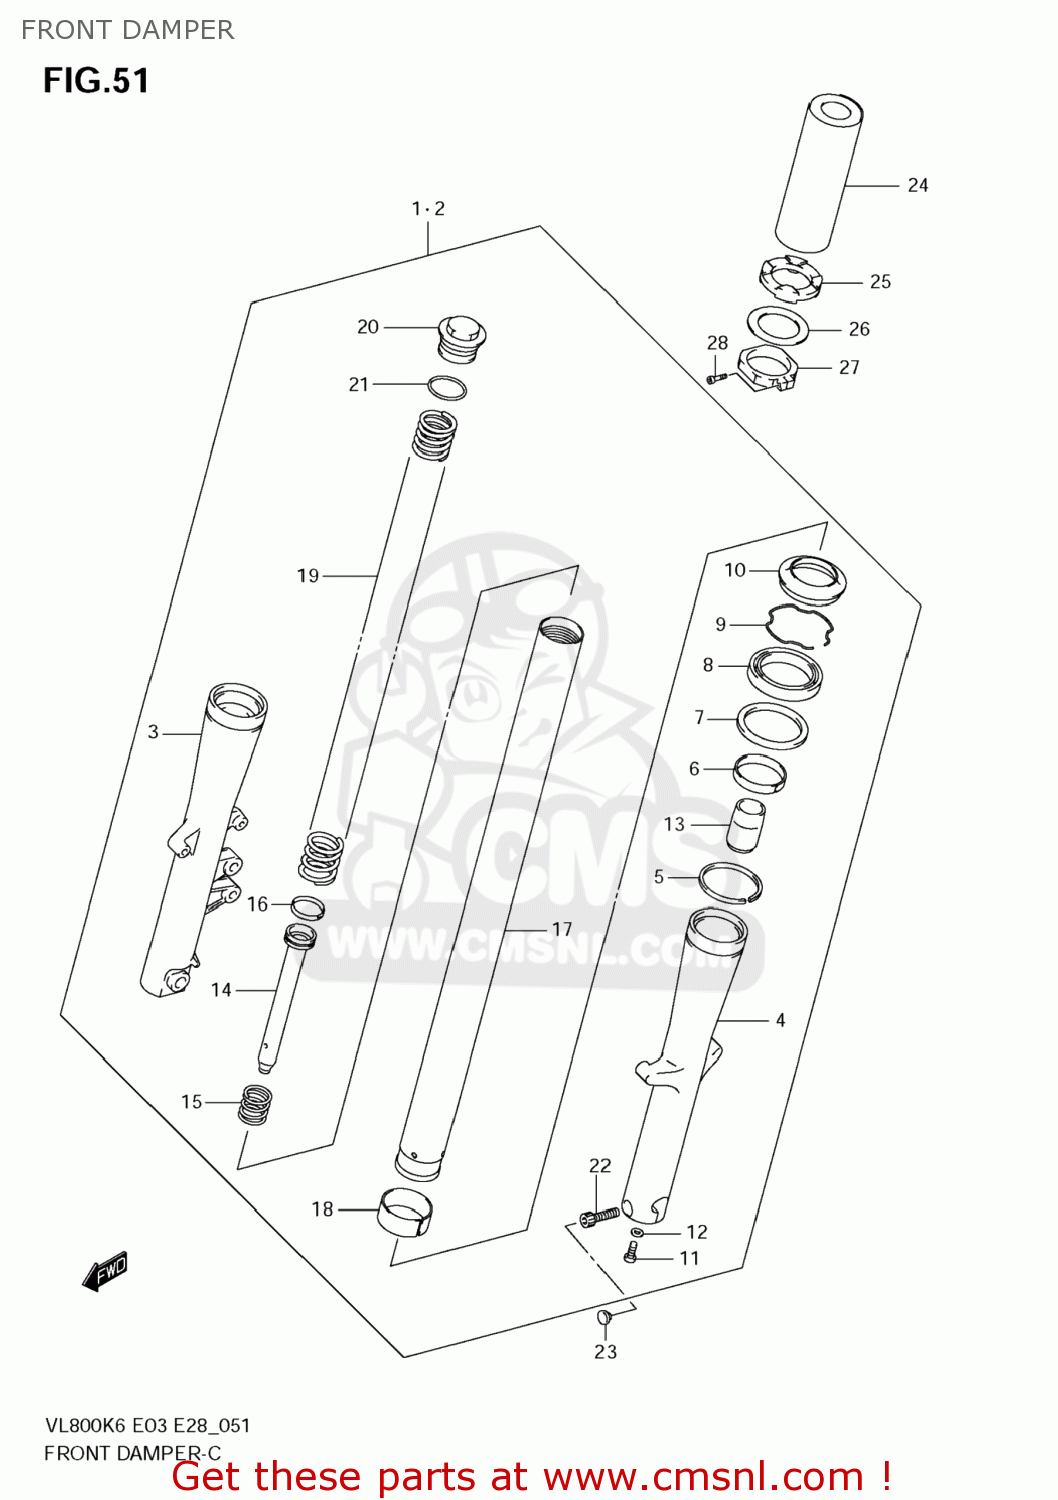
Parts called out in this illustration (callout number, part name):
1	DAMPER ASSY,FR FORK,R
2	DAMPER ASSY,FR FORK,L
3	TUBE,OUTER,R
4	TUBE,OUTER,L
5	GUIDE,CASE
6	BUSH,GUIDE
7	SPACER,SEAL
8	SEAL,OIL
9	CIRCLIP,FORK OIL SEAL
10	SEAL,DUST
11	BOLT
12	GASKET (NAS)
13	PIECE,OIL LOCK
14	SEAT,PIPE
15	SPRING,REBOUND
16	RING,PISTON
17	TUBE,INNER
18	BUSH,SLIDE
19	SPRING,FR
20	BOLT,FORK
21	O RING
22	BOLT
23	CAP(OD:12)
24	CASE,UNDER
25	SEAT,RUBBER
26	WASHER
27	SPACER
28	BOLT
